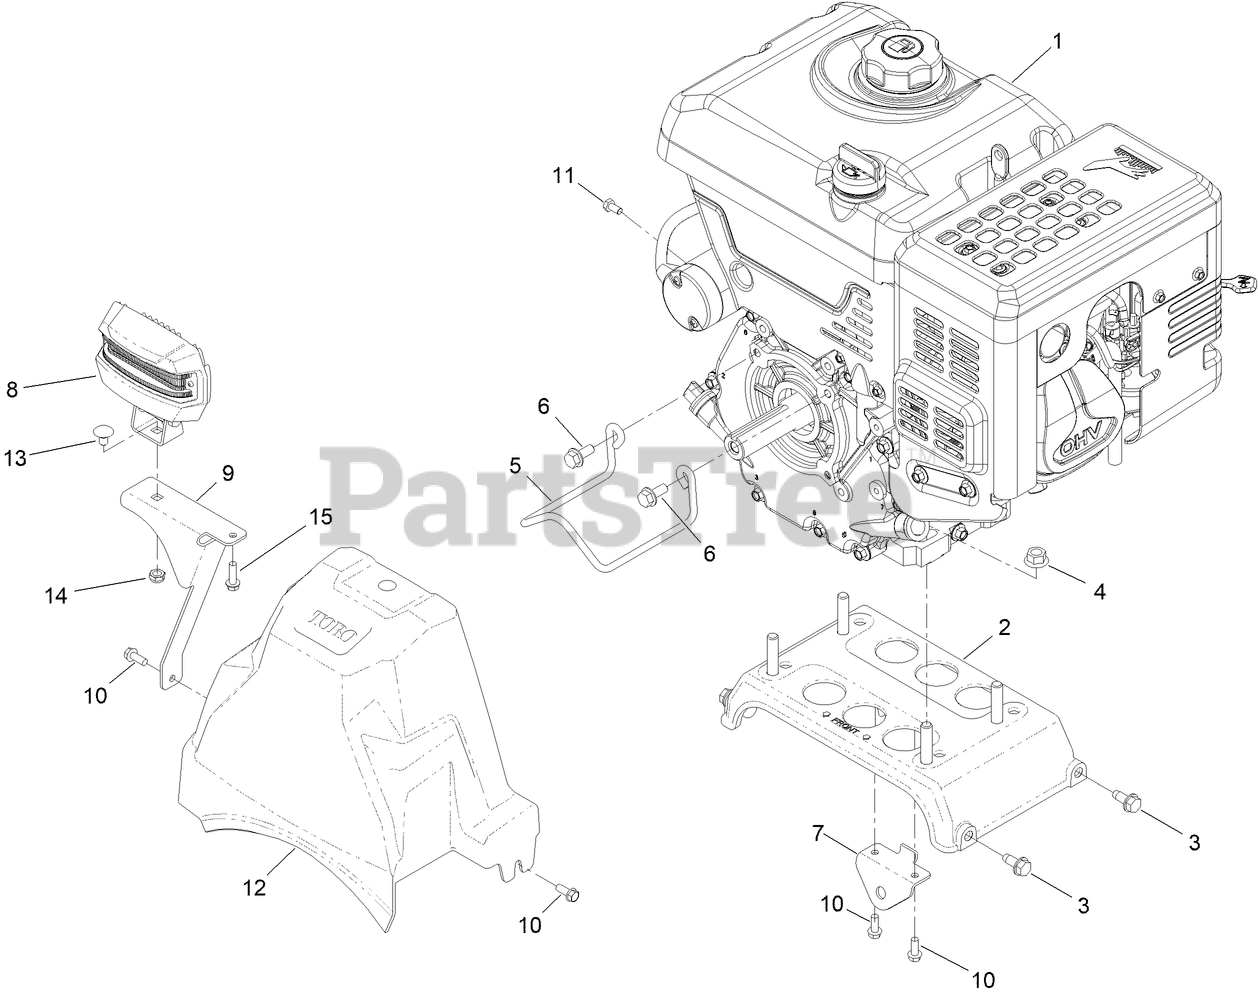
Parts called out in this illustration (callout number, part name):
1	ENGINE-LC180FDS-1
2	ENGINE PLATE ASM
3	SCREW-HWHTF
4	NUT-LOCK
5	GUIDE-BELT
6	SCREW-HH
7	BRACKET-CONTROL, TRACTION
8	LED LIGHT ASM
9	BRACKET-LIGHT
10	SCREW-HWH
11	SCREW-HH
12	COVER-BELT
13	BOLT-CARR
14	NUT-HEX
15	SCREW-PLASTITE, HWH
